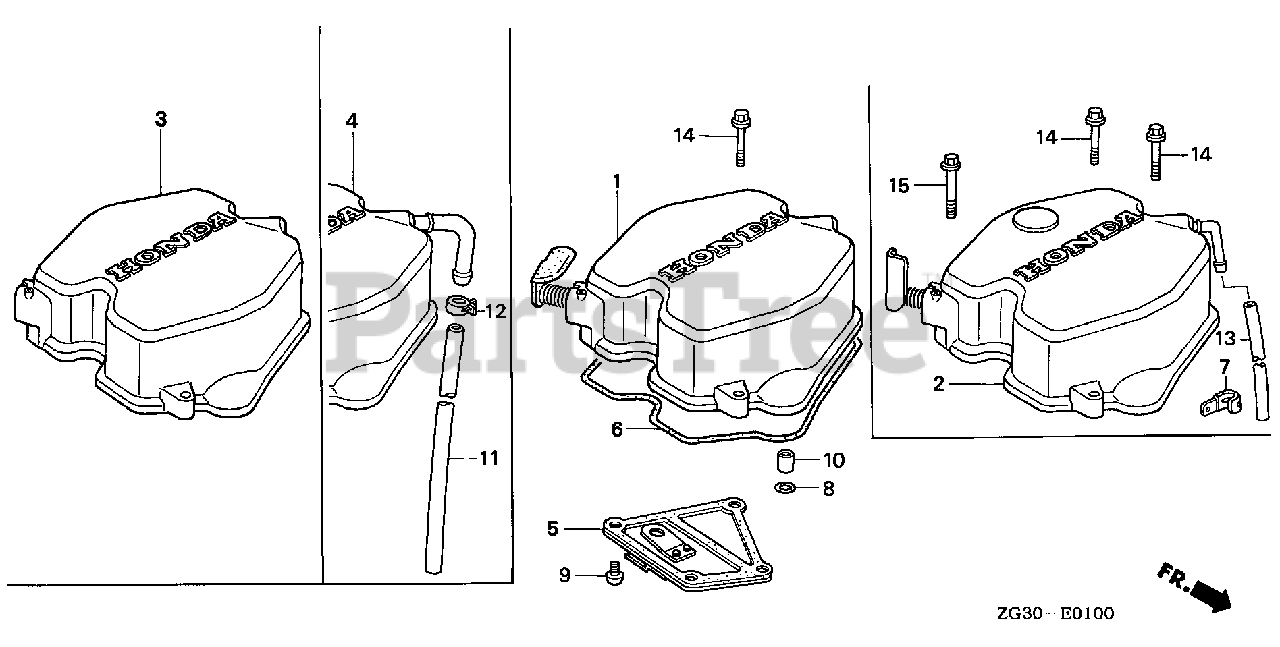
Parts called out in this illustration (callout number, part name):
1	COVER, CYLINDER HEAD (SEL)
5	PLATE, BREATHER
6	O-RING, HEAD COVER
9	SCREW, PAN (6X8)
10	PIN, DOWEL (6X10)
14	BOLT, FLANGE (6X28)
14	BOLT, FLANGE (6X32)
